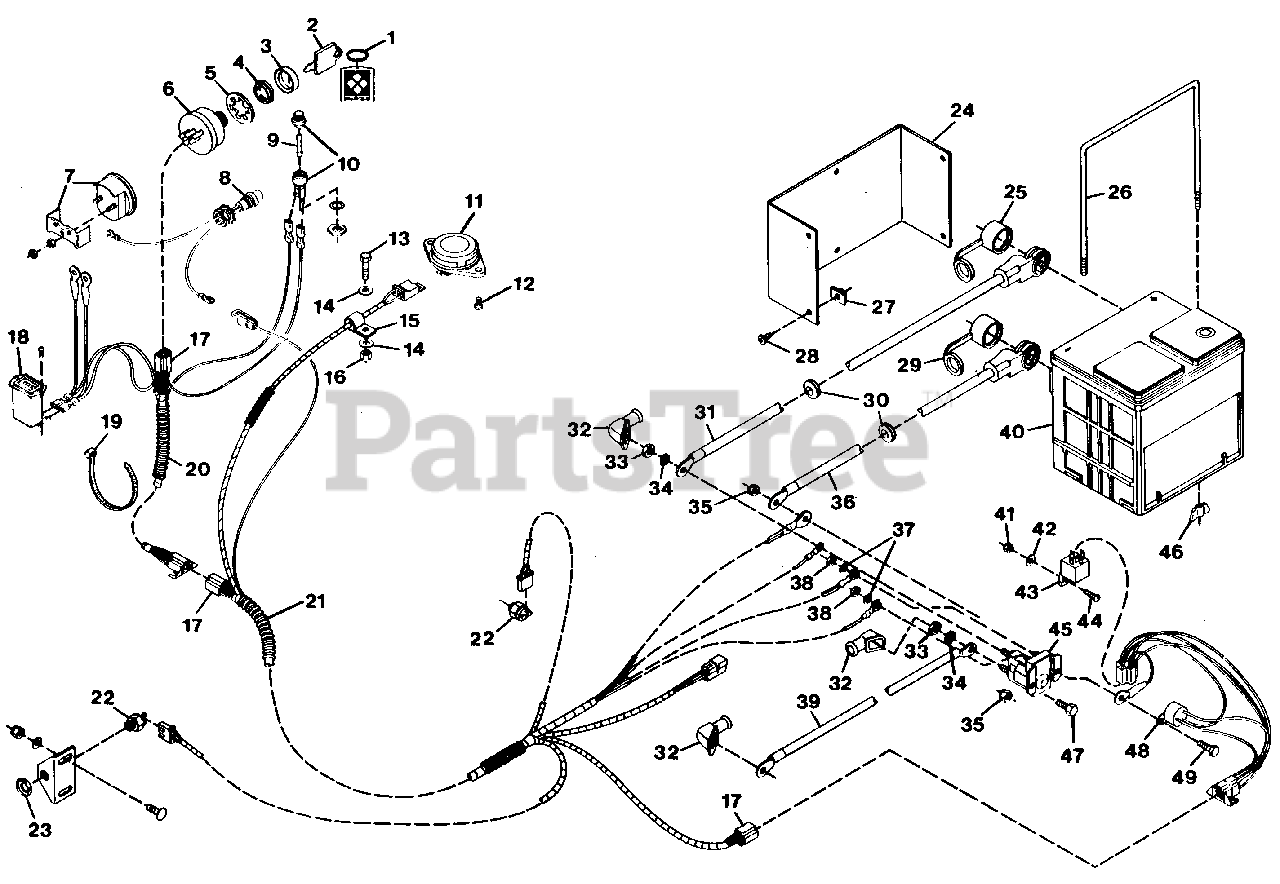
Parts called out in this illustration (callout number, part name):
1	Chain, Key
2	Key, Ignition Switch
3	Boot, for 9/16 Switch
4	Nut, 9/16-24 for Switch
5	Washer, Lock
6	Switch, Ignition
7	Gauge, Voltmeter
8	Light, Indicator
9	Fuse, 25 Amp
10	Fuse, Panel
11	Switch, Seat
12	Screw, Machine 1/4-20x.50
13	Bolt, Hex 5/16-18x.875
14	Washer, Flat .344x.688x.065
15	Clamp, Nylon
16	Nut, Lock 5/16-18
17	Connector
18	Hourmeter
19	Tie, Cable
20	Harness, Wrg. Inst. Panel
21	Harness, Wiring
22	Switch, Neutral Start
23	Nut, Stamped 9/16-18
24	Guard, Battery
25	Cover, Battery Positive Terminal
26	Rod, Battery
27	Nut, Retainer
28	Screw, Mach. 1/4-20x.625 Rd Hd
29	Cover, Battery Negative Terminal
30	Grommet
31	Cable, Electrical
32	Boot, Battery Cable
33	Nut, Jam 5/16-18
34	Washer, Lock 5/16 Int. Tooth
35	Nut, Lock 1/4-20
36	Cable, Electrical
37	Washer, Lock #10 Int. Tooth
38	Nut, Hex 10-32
39	Cable, Starter
40	Battery, 12 Volt
41	Nut, Lock 10-24
42	Washer, Flat .188x.438x.049
43	Relay
44	Screw, Mach. 10-24x.75 P/Hd
45	Switch, Magnetic
46	Nut, Wing 1/4-20
47	Bolt, Hex 1/4-20x1.00
48	Module, Time Delay
49	Bolt, Hex 1/4-20x1.25
